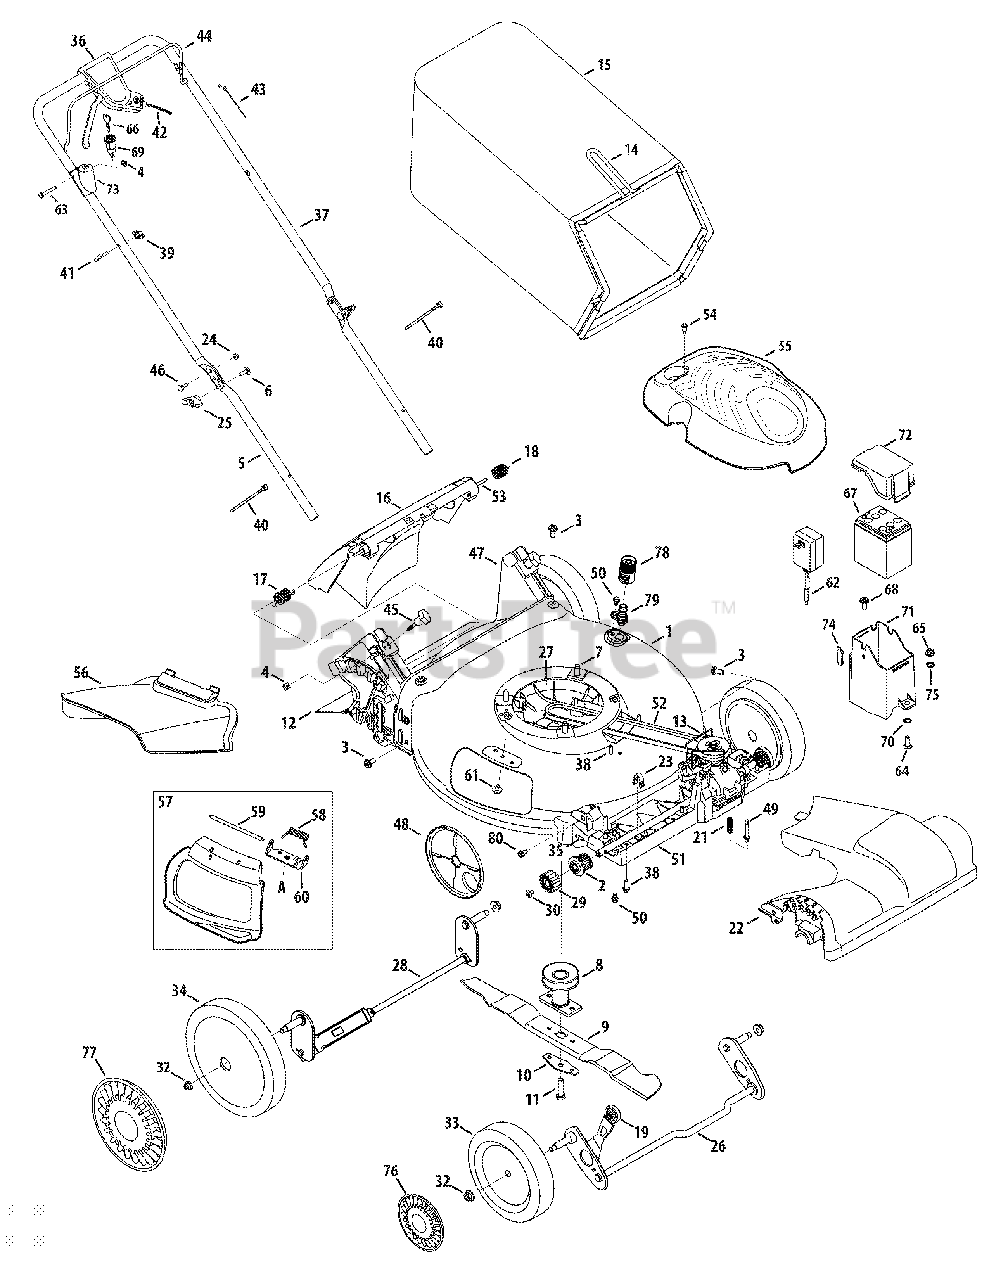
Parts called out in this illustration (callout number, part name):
1	Deck , 21"
1	Deck, 21" (Kohler Units)
2	Bearing Assembly
3	Screw, 5/16-14 x .750
4	Nut, Sq., 1/4-20
5	Lower Handle
6	Carriage Screw ,5/16-18
7	Screw, 3/8-16 x 1.00
8	Blade Adapter
8	Blade Adapter (Kohler Units)
9	Mulching Blade
10	Blade Bell Support
11	Screw, 3/8-24 x 1.50
12	Trailing Shield
13	Transmission Wire
14	Grass Catcher Frame
15	Grass Bag
15	Grass Bag (Kohler Units)
16	Rear Discharge Door Assembly
17	Torsion Spring - RH
18	Torsion Spring - LH
19	Adjustment Lever Knob
20	Screw, 1/4-20 x .500
21	Compression Spring
22	Front Cover
23	Front Axle Clip
24	Nut, Flange Lock, 1/4-20
25	Wing Knob
25	Wing Knob (Kohler Units)
26	Front Axle Assembly
27	Engine Baffle
28	Rear Axle Assembly
29	Spur Gear, 14T - RH
29	Spur Gear, 14T - LH
30	Screw, 1/4-20 x .390
32	Flange Lock Nut, 3/8-16
33	Front Wheel
34	Rear Wheel
35	Dowel Pin
36	Control Lever Assembly
37	Upper Handle
38	Screw, 1/4-15 x .750
40	Cable Tie
41	Rope Guide
42	Drive Cable
43	Control Cable
43	Control Cable (Kohler Units)
45	Wing Nut
45	Wing Nut (Kohler)
46	Sldr. Screw, .375 x .126 x 1/4-20
47	Water Nozzle
48	Wheel Dust Cover
49	Spring Body
50	Scr., Shldr., 1/4-20 x .50
51	Lower Tray
52	V-Belt
53	Pivot Rod
54	Screw, #12-16 x 1.00
55	Engine Shroud, Oyster Gray
56	Side Discharge Chute
56	Side Discharge Chute (Kohler Units)
57	Mulch Plug (Incl. 58-60)
58	Torsion Spring
59	Hinge Pin
60	Chute Deflector Bracket
61	Screw, 1/4-20 x .500
62	Battery Charger
63	Screw, 1/4-20 x 1.75
64	Bolt, Carr., 5/16-18 x 1.00
65	Nut, Hexlk, 5/16-18
66	Key
67	Battery
68	Scr., Sldr., 5/16-14 x .972
69	Key Switch
70	Speed Nut
71	Battery Housing
72	Battery Housing Top
73	Electric Start Housing
74	Lid Seal
75	Washer, Bell, .340 x .872 x .080
76	Hubcap, Grey
76	Hubcap, Yellow
77	Hubcap, 11", Grey
78	Water Nozzle Adapter
80	Screw 1/4-20 x .70
